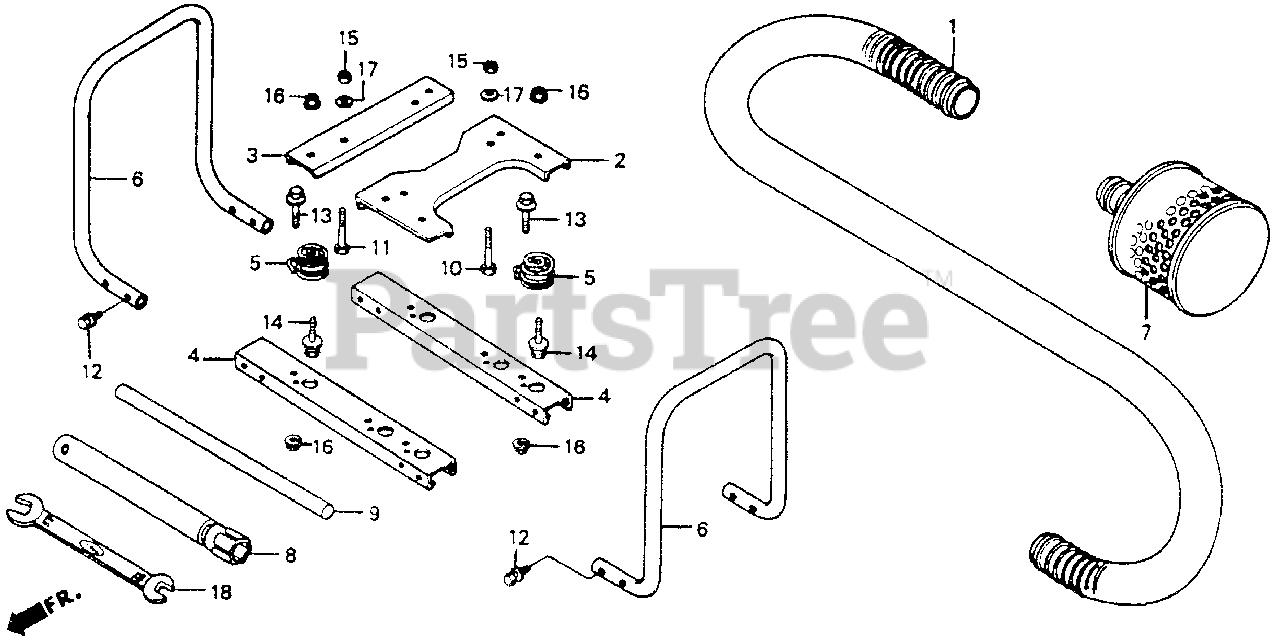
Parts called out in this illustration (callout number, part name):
1	HOSE, SUCTION (4.5M)
2	BRACKET A, MOUNTING
3	BRACKET B, MOUNTING
4	BED, FRAME
5	SPRING, MOUNT
6	HANDLE, CARRYING
7	STRAINER (NOT AVAILABLE)
8	WRENCH, SPARK PLUG
9	HANDLE, BOX WRENCH
10	BOLT, HEX. (8X28)
11	BOLT, HEX. (8X35)
12	BOLT-WASHER (8X20)
13	BOLT-WASHER (8X20)
14	BOLT-WASHER (8X25)
15	NUT, HEX. (8MM)
16	NUT, FLANGE (8MM)
17	WASHER, PLAIN (8MM)
18	SPANNER (12X17) (NOT AVAILABLE)
